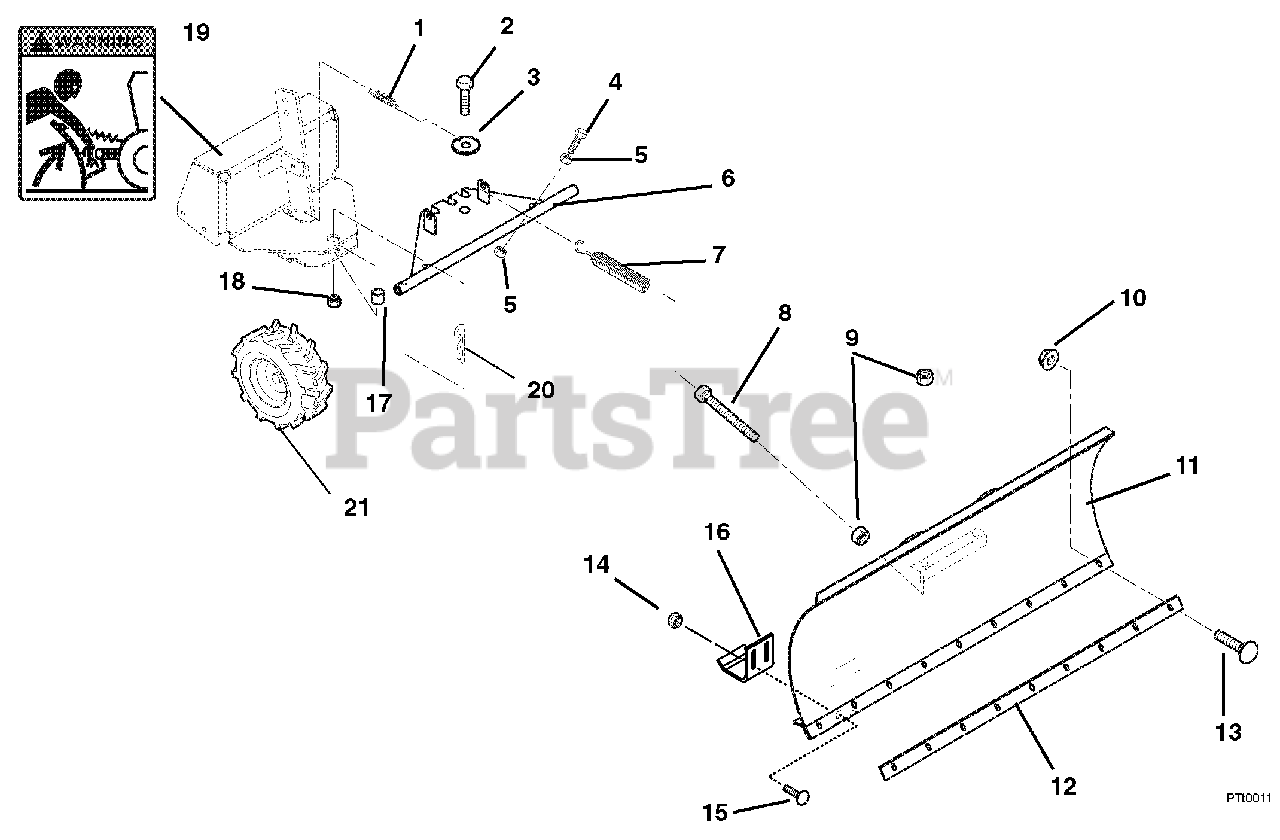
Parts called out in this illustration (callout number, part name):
1	SPRING,LATCH
2	BLT-HEX .75-10X3.00 GR5 YWZC
3	WSHR, SPECIAL
4	@BLT-HEX .50-13X2.00 GR5 YWZC
5	@NUT-HEX .50-13 YWZC
6	WMT,PIVOT PLATE
7	SPRING,BLADE ADJUSTMENT
8	BLT,HEX 3/8-16X4.00 FULL TH'D
9	@NUT-HEX .38-16 YWZC
10	@NUT-LK-TOP-FLG .31-18 YWZC
11	DOZER BLADE, 54" WELDMENT 12GA
12	SCRAPER BLADE, 54" DOZER BLADE
13	@BLT-RDHDSQNK .31-18X.75 G5YZ
14	@NUT-HEX .38-16 YWZC
15	@BLT-RDHDSHSQNK.38-16X1.0 G5YZ
16	SKID SHOE
17	SPACER, .753X1.00X1.60
18	NUT-LK-JAM-NYL .75-10 YWZC
19	DECAL, PINCH POINT
20	PIN-HAIR-INT .15X2.937 YWZC
21	ASSY,WHEEL & TIRE 18X6.5 S-HOG
